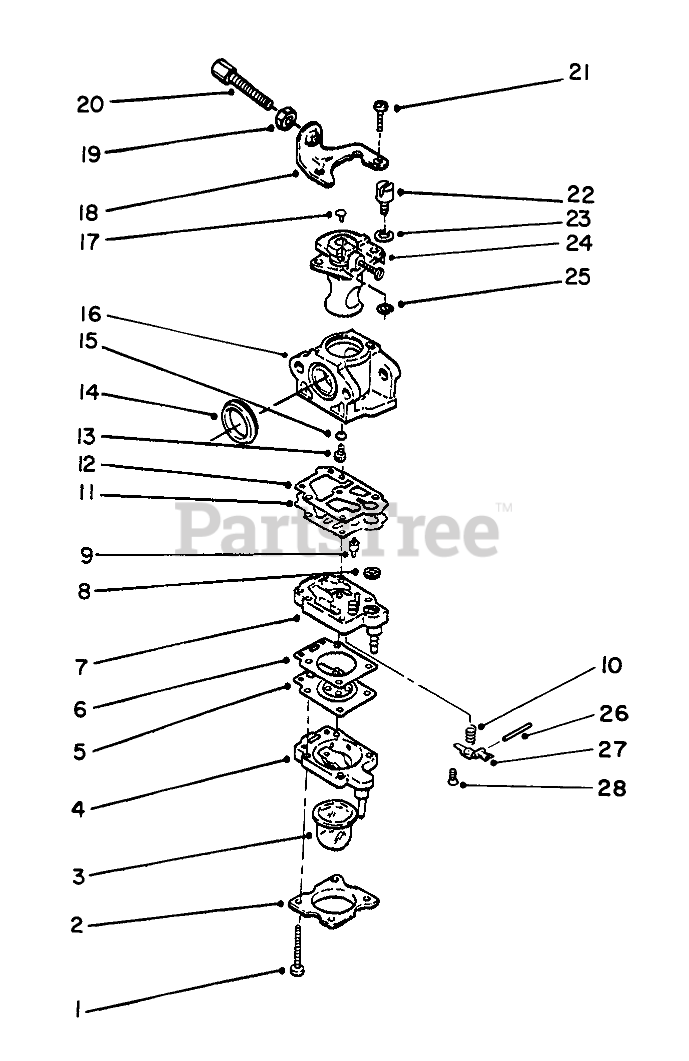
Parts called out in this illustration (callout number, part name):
1	Screw
2	Cover-Primer
3	PRIMER PUMP
4	Body-Primer
5	DIAPHRAGM
6	DIAPHRAGM GASKET
7	Body Assembly-Fuel Pump(Incl. Ref. #8)
8	SCREEN
9	NEEDLE VALVE
10	Spring
11	DIAPHRAGM
12	DIAPHRAM GASKET
13	MAIN JET
14	RUBBER CARB GASKET
15	MAIN JET O-RING
16	Body-Carburetor (Ref.)
18	BRACKET
19	LOCKNUT
20	ADJUSTING SCREW
21	SCREW
22	Holder-Wire
23	WASHER
24	THROTTLE VALVE
27	Lever
28	Screw
